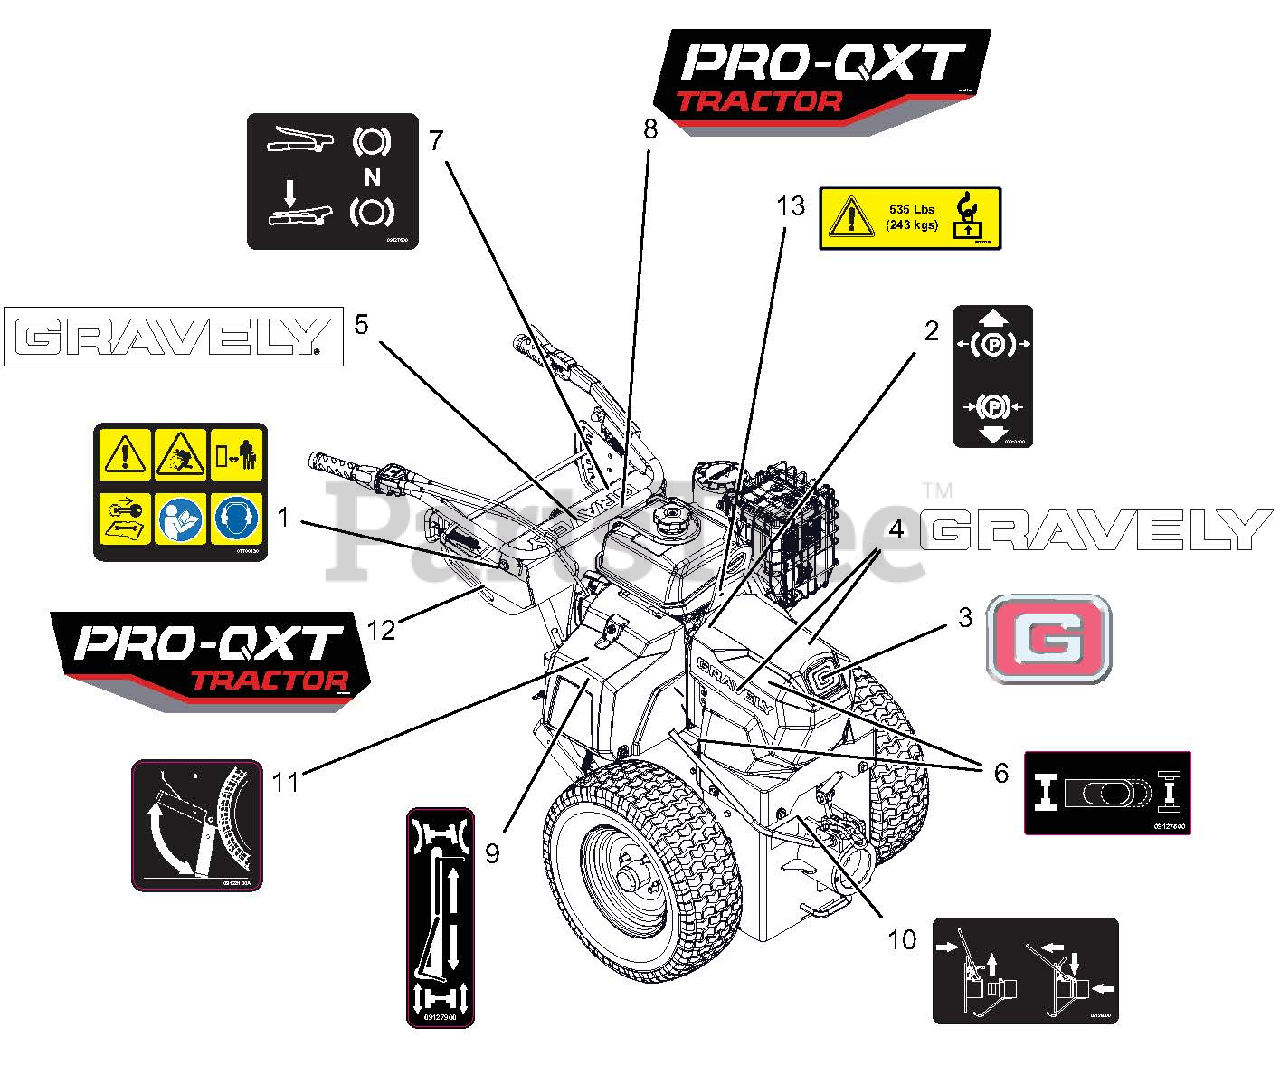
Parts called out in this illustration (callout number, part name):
1	DECAL, SAFETY
2	DECAL, PARKING BRAKE LEVER
3	DECAL, GRAVELY BRAND
4	DECAL, 9.5" GRAVELY LOGO
5	DECAL, 13.5" GRAVELY LOGO
6	DECAL, TRANSAXLE BYPASS
7	DECAL, OPERATOR CONTROLS
8	DECAL, LH PRO-QXT
9	DECAL, AXLE LOCK
10	DECAL, ATTACHMENT LOCK
11	DECAL, KICKSTAND OPERATION
12	DECAL, RH PRO-QXT
13	DECAL, TRACTOR WEIGHT
